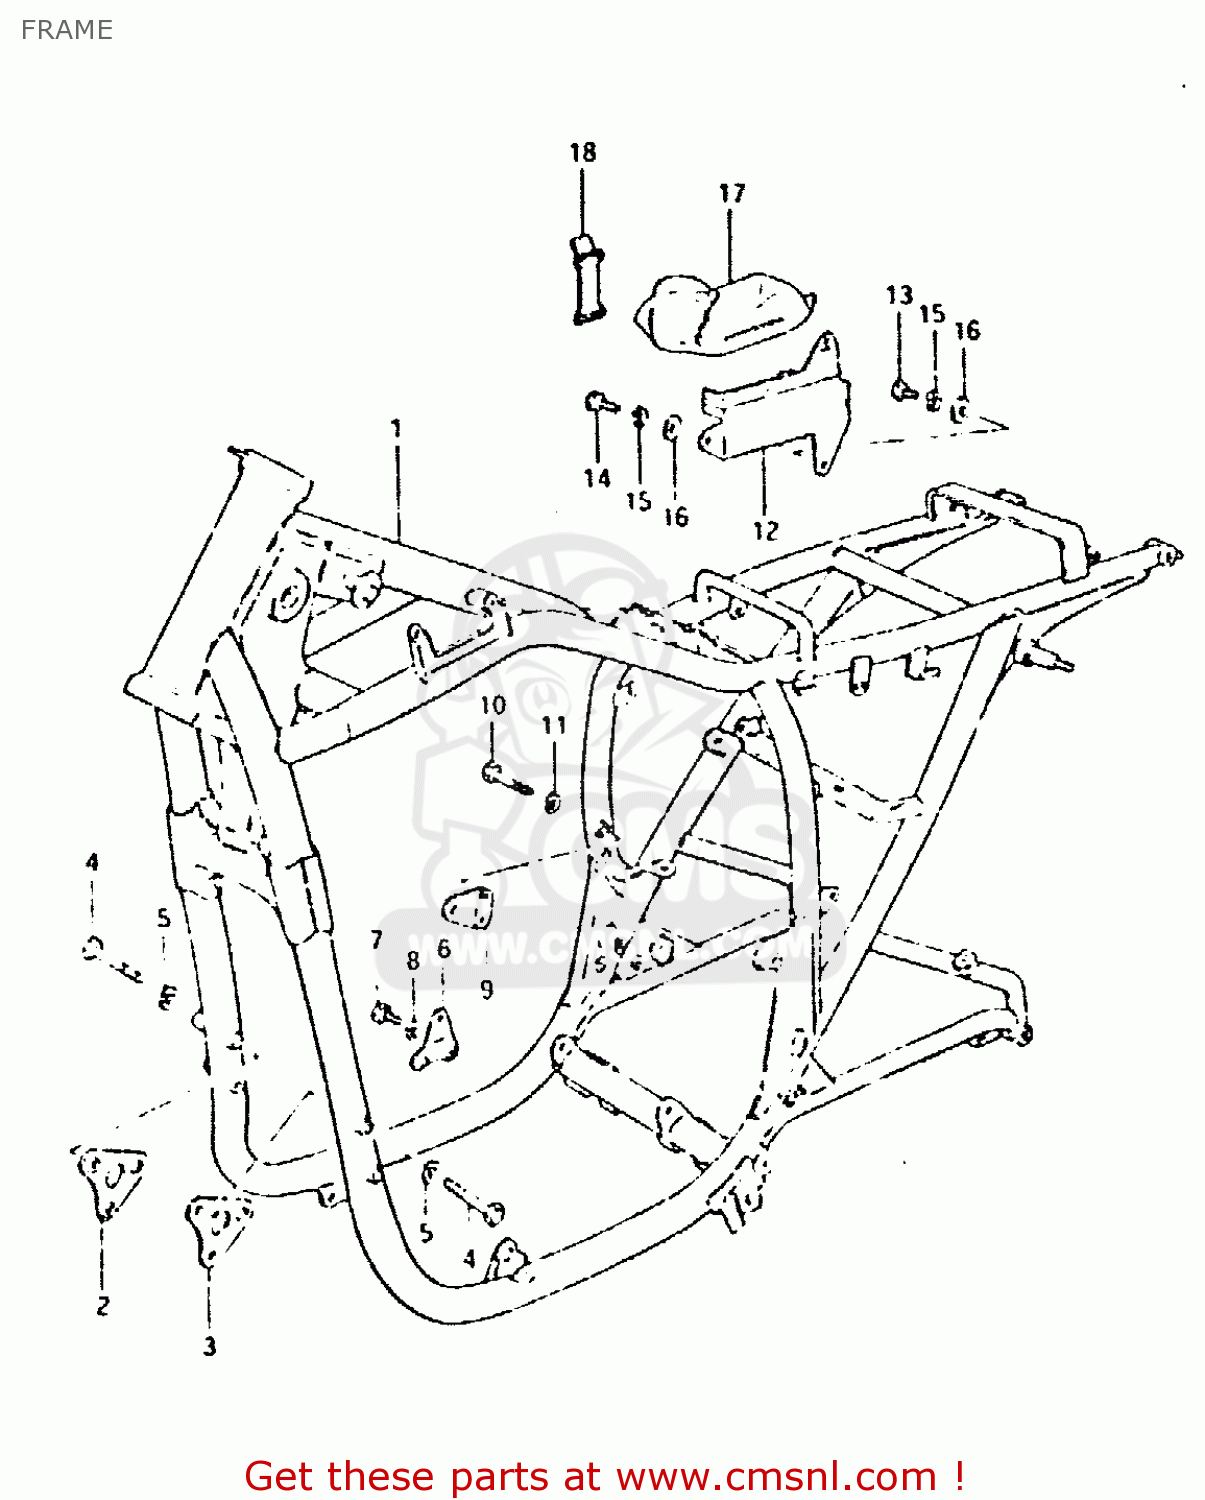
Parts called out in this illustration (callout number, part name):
1	FRAME
2	PLATE,ENGINE MOUNTING
3	PLATE,ENGINE MOUNTING
4	BOLT
5	LOCK WASHER
6	PLATE,ENGINE MOUNTING
7	BOLT
8	LOCK WASHER
9	PLATE,ENGINE MOUNTING
10	BOLT 8X45
11	LOCK WASHER
12	HOLDER,TOOL
13	SCREW 6X12
14	SCREW
15	LOCK WASHER
16	WASHER
17	TOOL ASSY
18	BAND
